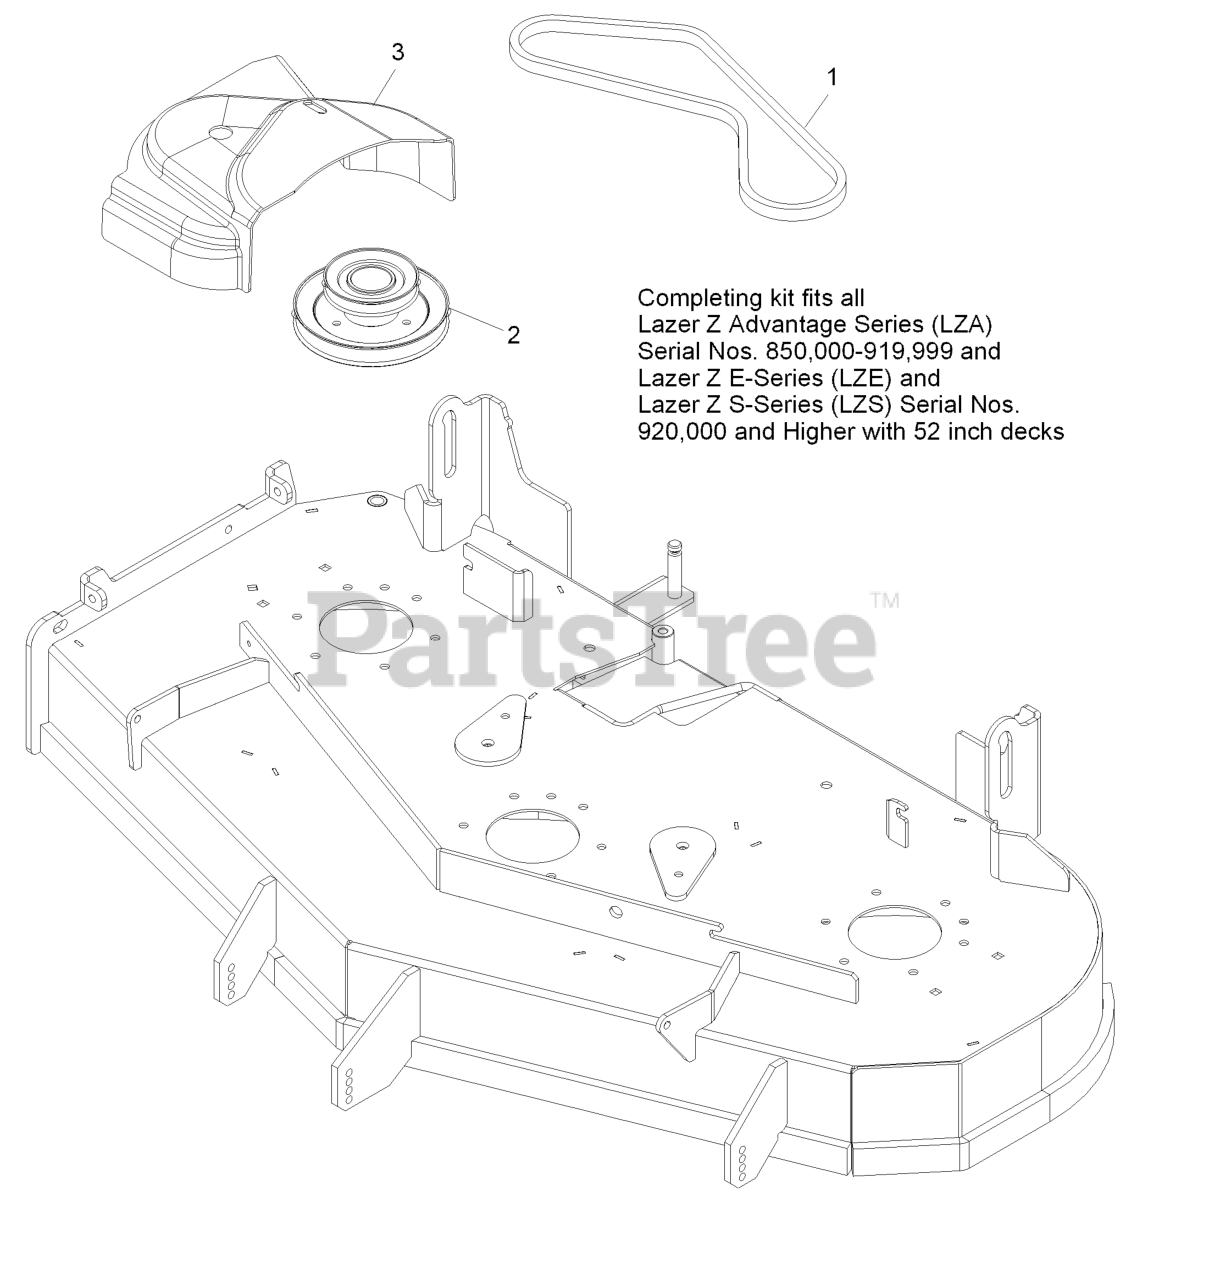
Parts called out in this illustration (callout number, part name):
1	Belt, Blower Drive 52
2	Jackshaft,Uv Drive 524 Splined
3	Cover,Belt Uv 52
